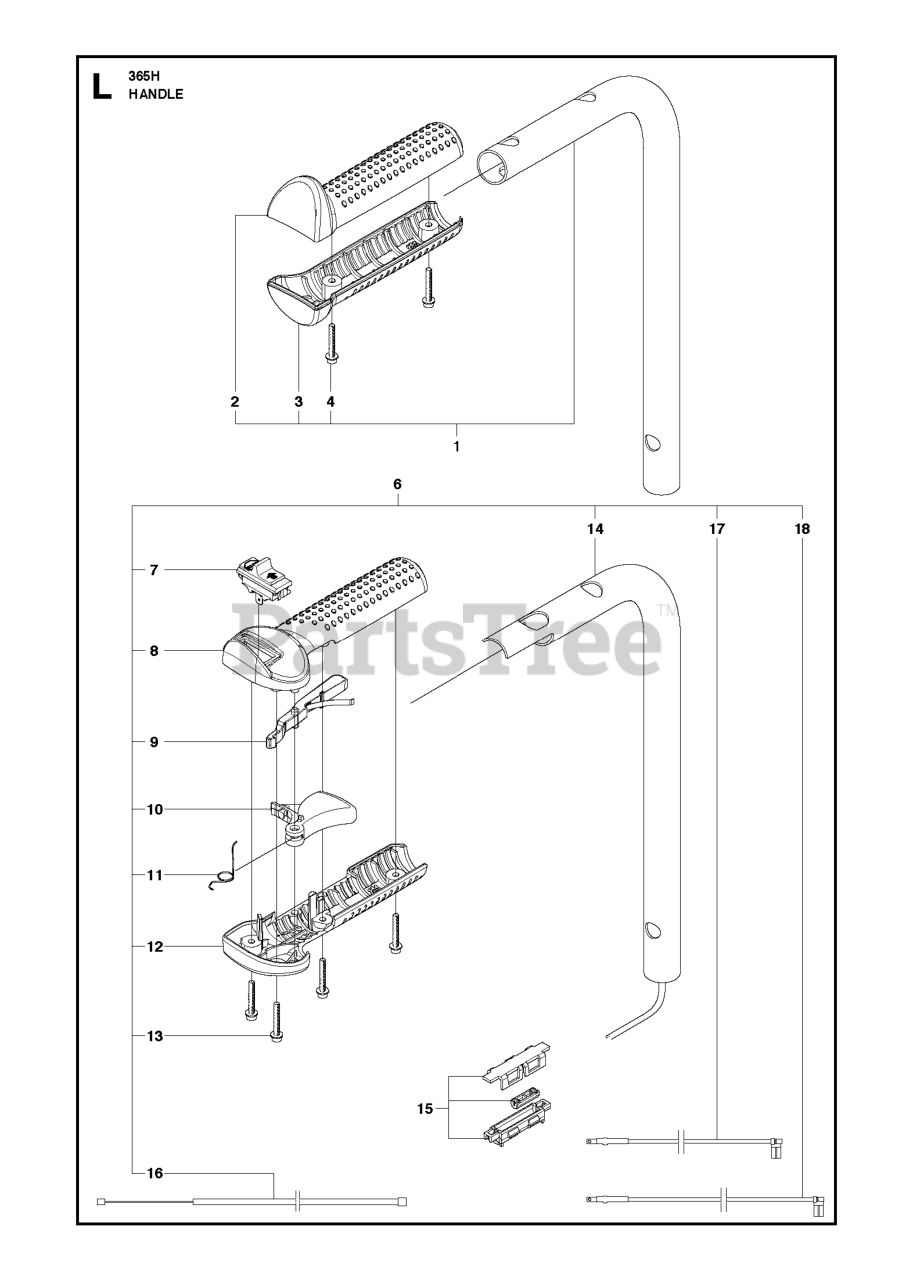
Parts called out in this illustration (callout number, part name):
2	HANDLE HALF
3	HANDLE HALF
7	START/STOP SWITCH
8	HANDLE HALF
9	THROTTLE LOCKOUT ASS
10	THROTTLE TRIGGER
12	HANDLE HALF
14	HANDLE TUBE
15	QUICK COUPLING ASSY
16	THROTTLE WIRE ASSY
17	CABLE
18	CABLE
